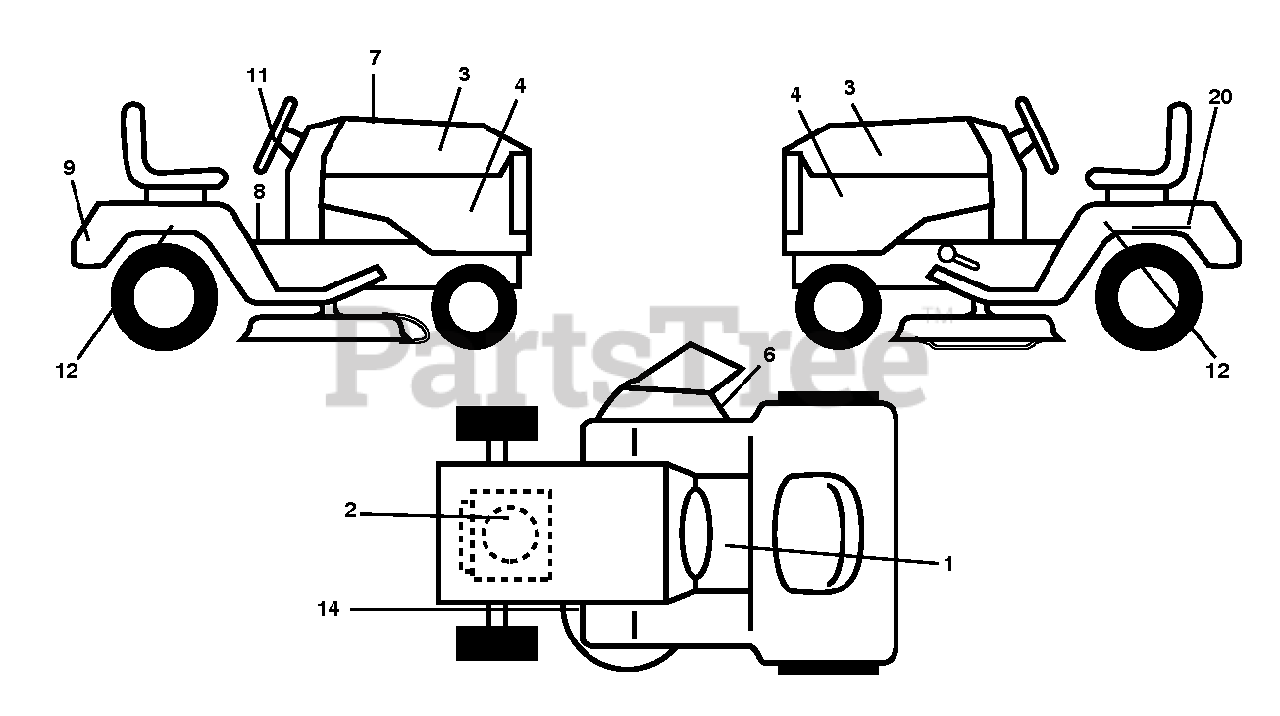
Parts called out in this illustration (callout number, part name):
1	DCL.WARNING.SPARK.IGNITION.CA
2	DECAL.ENG.BS.20HPXRD.SL.278416
3	DECAL.HOOD.POULAN.PRO.SET
6	DECAL.MOWER.WARN.KEEP.HAND.AWY
8	DECAL.WARNING.2007.ENG/FR
9	DECAL.REAR.FNDR.LOGO.POULAN.PR
11	DECAL.STEER.WHEEL.POULAN.PRO
14	DECAL.V-BELT.SCH.42/46"MEC/ELE
20	DECAL BTRY SYMBOLS
